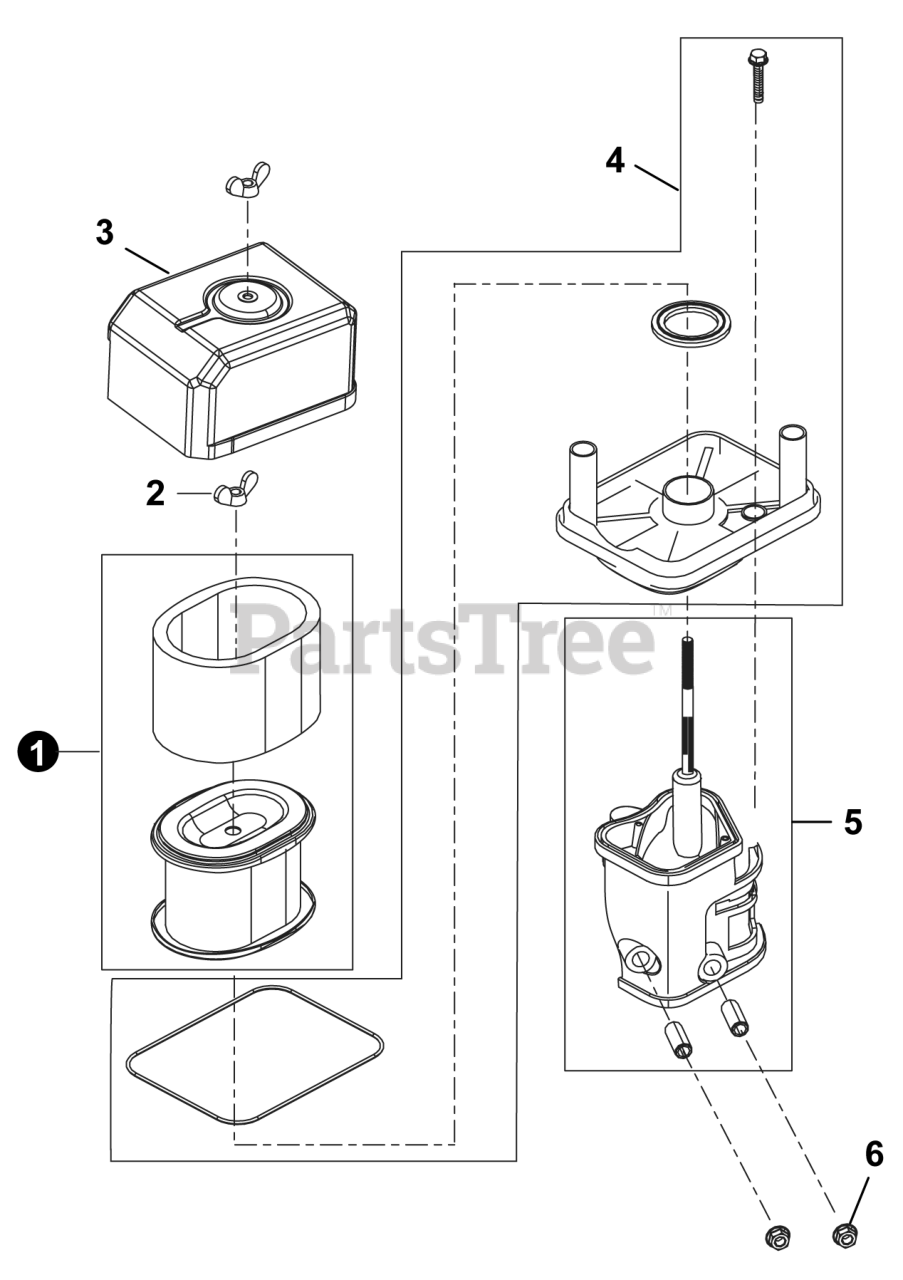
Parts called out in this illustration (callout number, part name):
1	ELEMENT, AIR CLEANER
2	NUT, WING
3	COVER, AIR FILTER
4	BASE, AIR FILTER
5	MOUNT, AIR FILTER HOUSING
